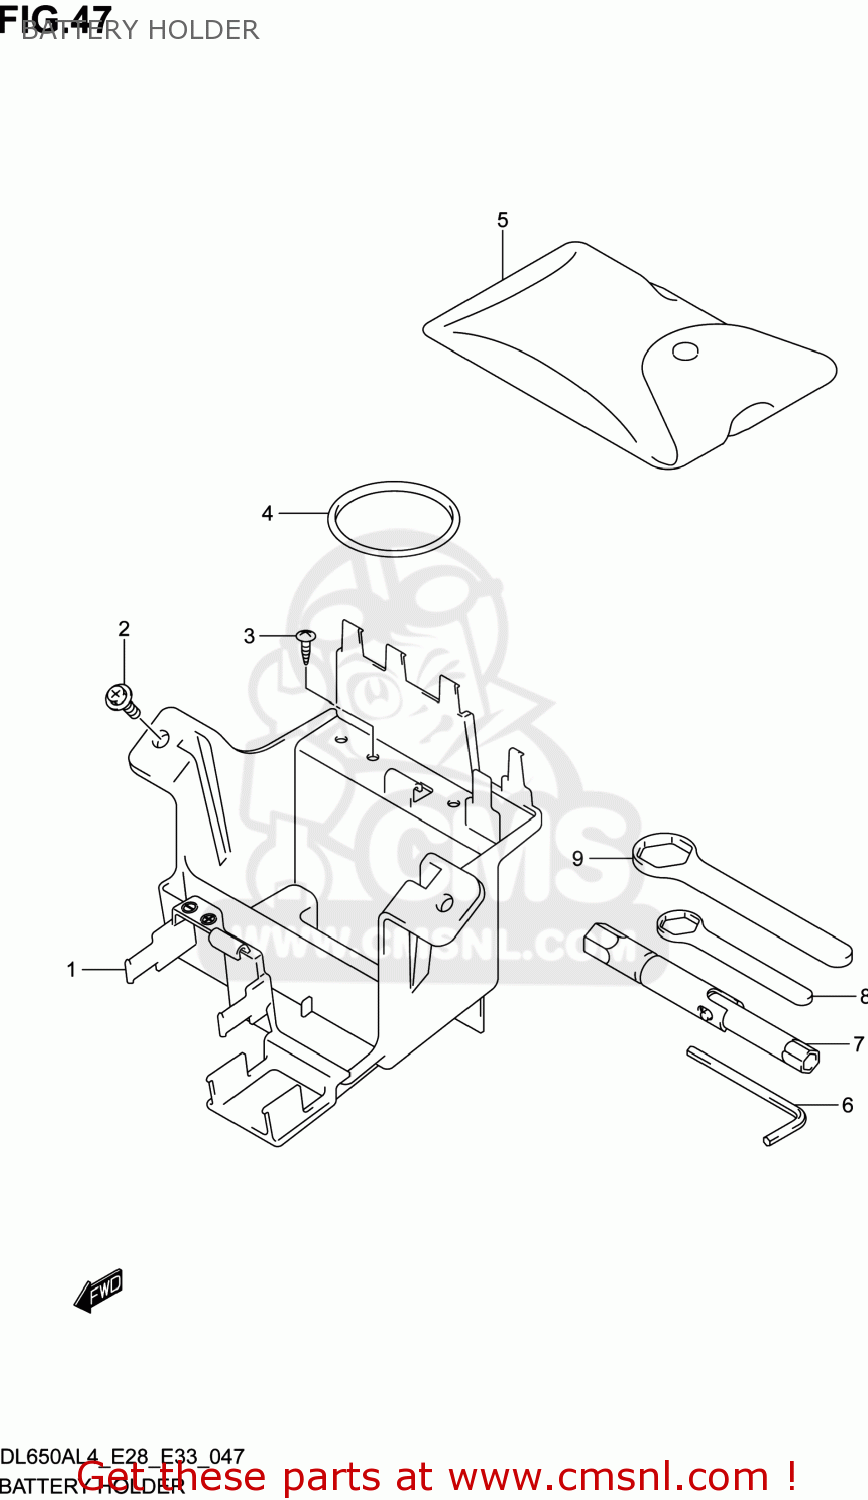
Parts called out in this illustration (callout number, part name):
1	HOLDER,BATTERY
2	BOLT(6X12)
3	SCREW(5X16)
4	O RING(D:3.5,ID:62.6)
5	TOOL ASSY
6	HEXAGON SPANNER,5
7	SPARK PLUG WRENCH
8	RING SPANNER(22)
9	RING,SPANNER(24)
